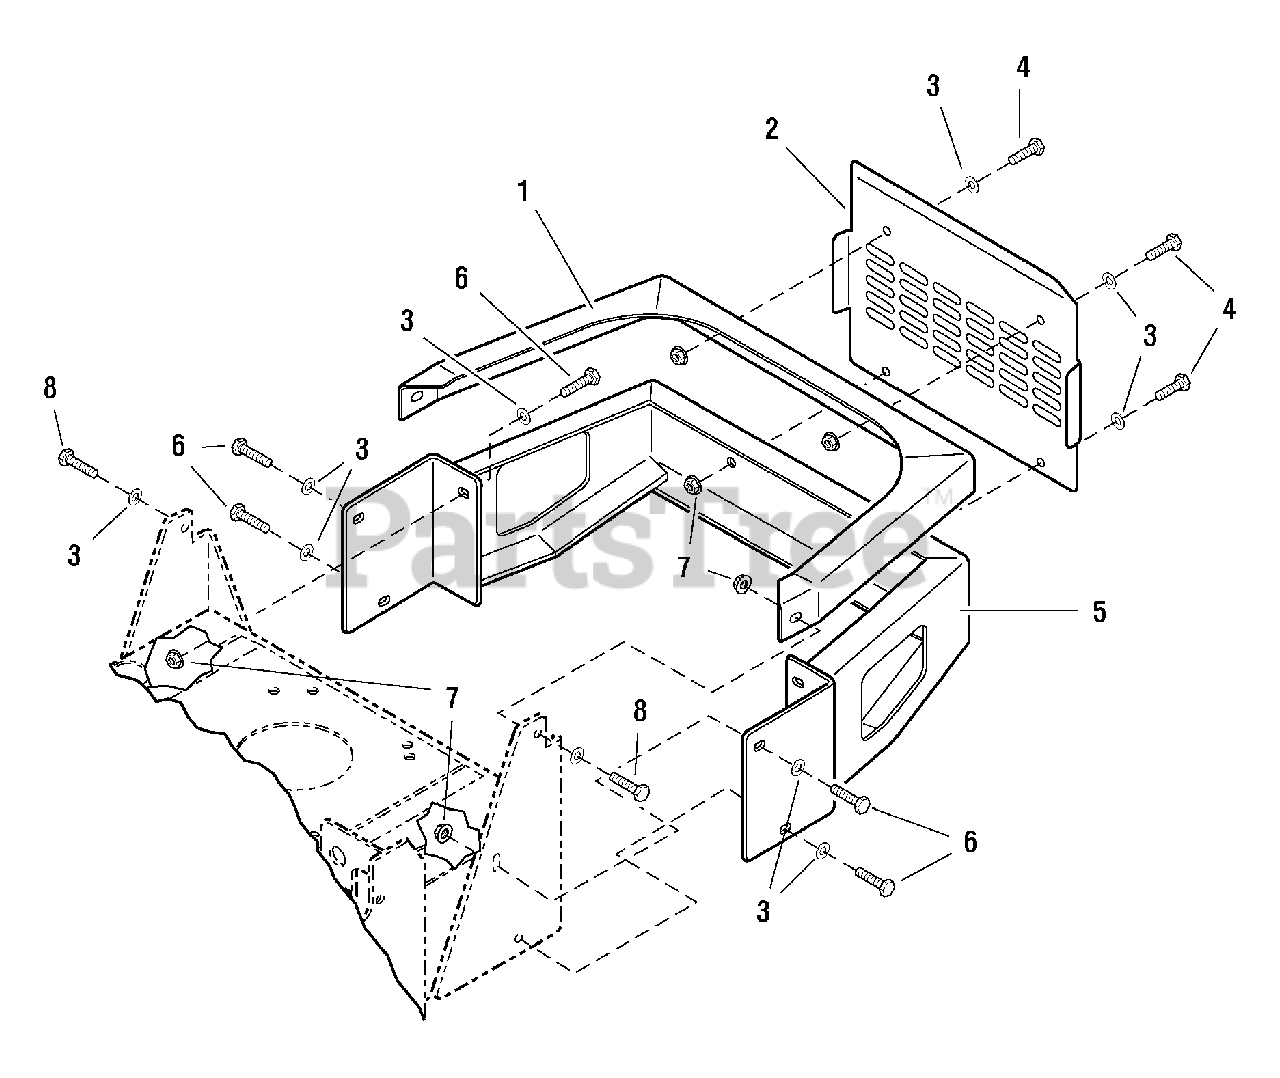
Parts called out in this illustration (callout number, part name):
1	BUMPER, Top, Orange
1	BUMPER, Top, Red
2	SHIELD, Bumper, Orange
2	SHIELD, Bumper, Red
3	WASHER, SAE, 5/16
4	CAPSCREW, Hex Head, 5/16-18 x 3/4
5	BUMPER, Lower, Orange
5	BUMPER, Lower, Red
6	CAPSCREW, Hex Head, 5/16-18 x 1-1/4
7	NUT, Hex Serrated Flange, 5/16-18
8	CAPSCREW, Hex Head, 5/16-18 x 1
